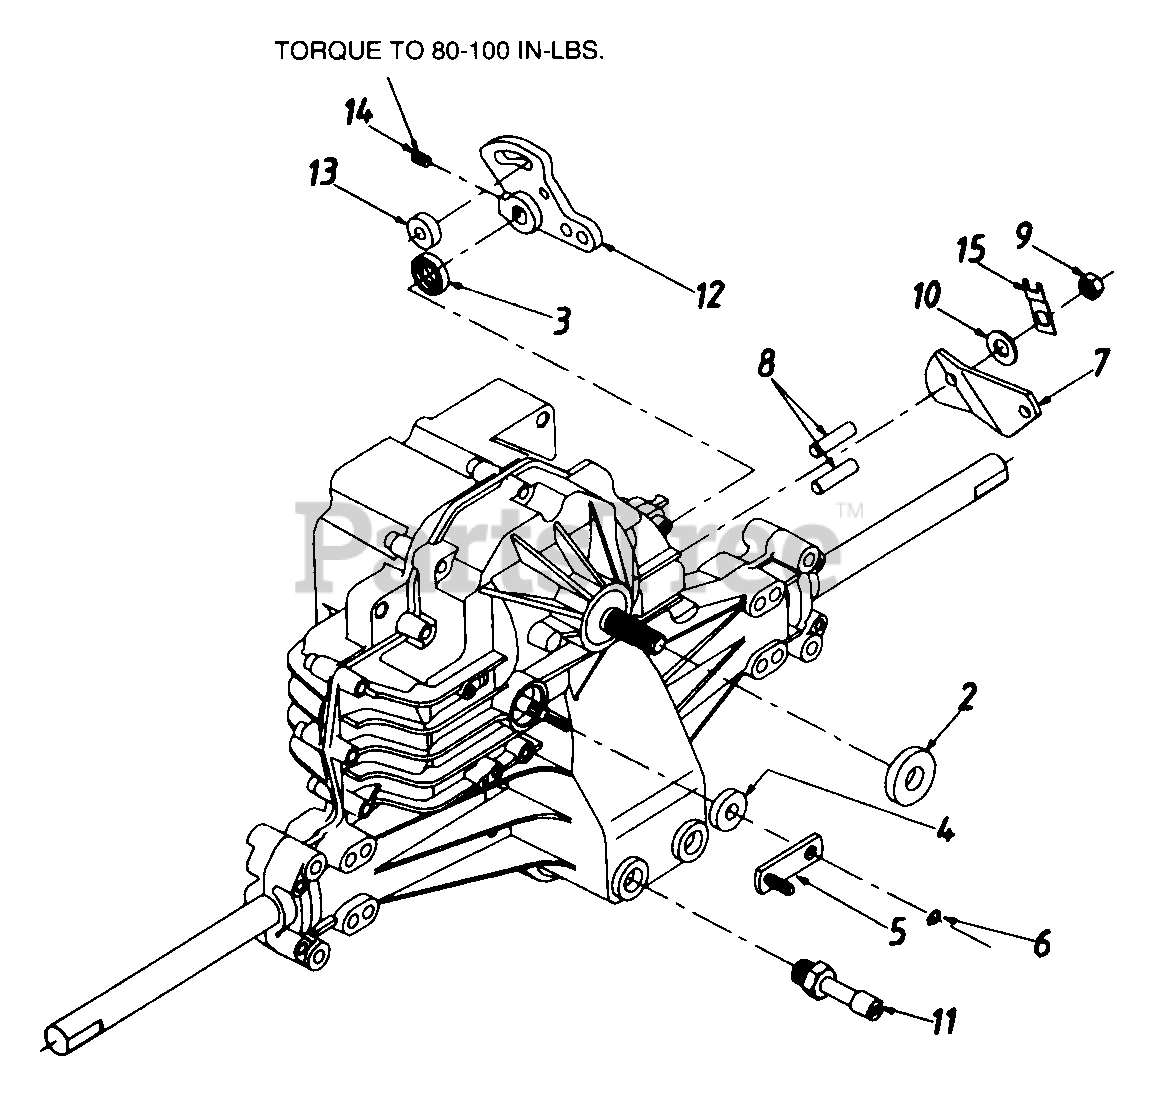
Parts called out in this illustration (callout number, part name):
1	Transmission Comp.
2	Seal - Lip
3	Seal - Lip
4	Seal - Lip 10 x 25 x 7
5	Arm - Bypass
6	Ring - Retaining
7	Arm - Actuating
8	Pin - Actuating
9	Nut - Hex Lock 5/16-24 UNJC
10	Washer 7/16" x 7/8" x .060"
11	Breather Ass'y.
12	Arm - Control
13	Puck - Dampener
14	Set Screw
15	Strap, Locking
